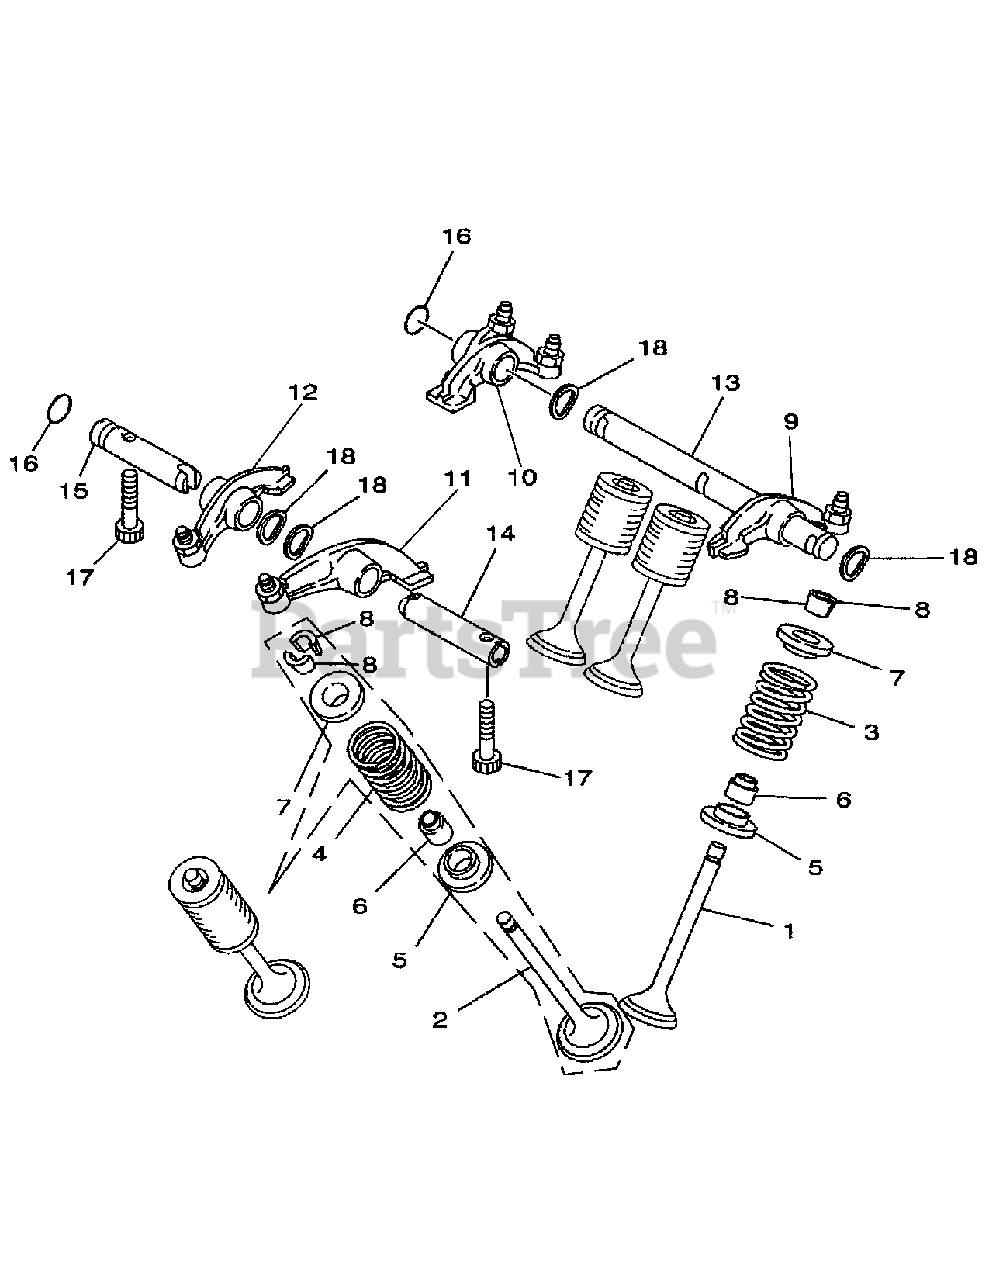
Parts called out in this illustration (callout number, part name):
1	Inlet Valve
2	Outlet Valve
3	Spring-Inlet Valve
4	Spring-Outer Valve
5	Spring Seat-Valve
6	Fuel Shield Cover
7	Cotter Seat-Valve
8	Lock Clip-Valve
9	Rocker Arm-Inlet I
10	Rocker Arm-Inlet II
11	Swing Arm-Comp Out II
12	Rocker Arm-Outlet I
13	Rocker Arm Shaft I
14	Rocker Arm Shaft III
15	Rocker Arm Shaft II
17	Screw-Cylinder M6X20
18	Washer 12.5×34×0.4
